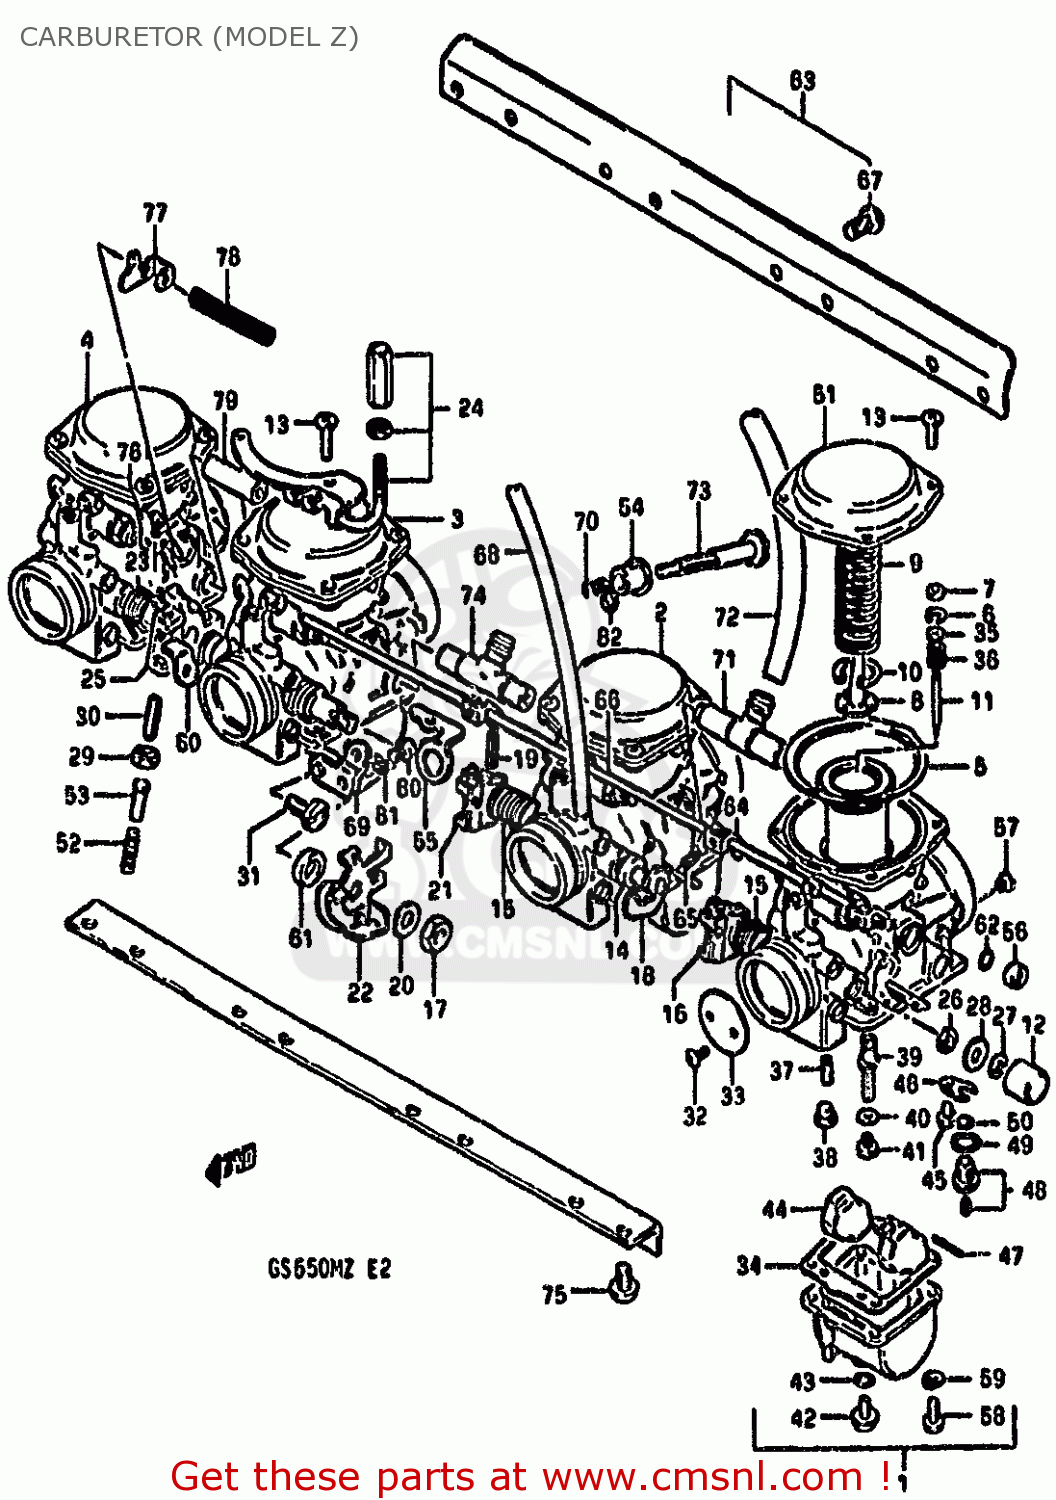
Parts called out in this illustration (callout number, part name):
1	CARBURETOR,LH
2	CARBURETOR,ML
3	CARBURETOR,MR
4	CARBURETOR,RH
5	DIAPHRAGM ASSEMBLY
6	CLIP,NEEDLE
7	RING
8	HOLDER,GUIDE
9	SPRING
10	E RING
11	NEEDLE, JET (5F42-3)
12	CAP
13	SCREW
14	GASKET,THROTTLE SHAFT (NAS)
15	SPRING,THROTTLE SHAFT
16	SHAFT,THROTTLE
17	NUT 8MM
18	SHAFT,THROTTLE
19	PIN,THROTTLE SHAFT
20	WASHER
21	LEVER,THROTTLE SHAFT
22	LEVER ASSEMBLY,THROTTLE
23	SPRING,THROTTLE SHAFT
24	BRACKET,THROTTLE CABLE
25	SHAFT,THROTTLE
26	SEAL
27	E RING
28	GASKET,THROTTLE SHAFT (NAS)
29	NUT
30	SCREW
31	SCREW
32	SCREW
33	VALVE,THROTTLE (BUTTERFLY)
34	GASKET,FLOAT CHAMBER (NAS)
35	WASHER
36	SPRING
37	JET
38	PLUG,NEEDLE JET
39	JET, NEEDLE (X-6)
40	WASHER,NEEDLE NOZZLE
41	JET
42	PLUG,DRAIN
43	GASKET (NAS)
44	FLOAT
45	SCREW 4X6
46	PLATE,NEEDLE VALVE FITING
47	PIN,FLOAT
48	VALVE ASSEMBLY,NEEDLE
49	O-RING,NEEDLE VALVE
50	FILTER
51	COVER,DIAPHRAGM
52	SPRING,THROTTLE SCREW
53	PIN,THROTTLE LEVER
54	BUSH
55	BRACKET,THROTTLE ADJUST
56	CAP,STARTER VALVE
57	JET,AIR
58	SCREW
59	LOCK WASHER
60	SHAFT,THROTTLE
61	WASHER
62	O RING
63	CARBURETOR ASSEMBLY
64	LEVER
65	SCREW
66	SHAFT,STARTER
67	SCREW
68	HOSE
69	BRACKET,THROTTLE ADJUST
70	SPRING
71	NIPPLE
72	HOSE
73	SCREW
74	NIPPLE,CARBURETOR
75	SCREW 6X12
76	LEVER,CHOKE CABLE
77	PLATE,CHOKE CABLE
78	SPRING,CHOKE CABLE
79	NIPPLE
80	SCREW
81	LOCK WASHER
82	WASHER
